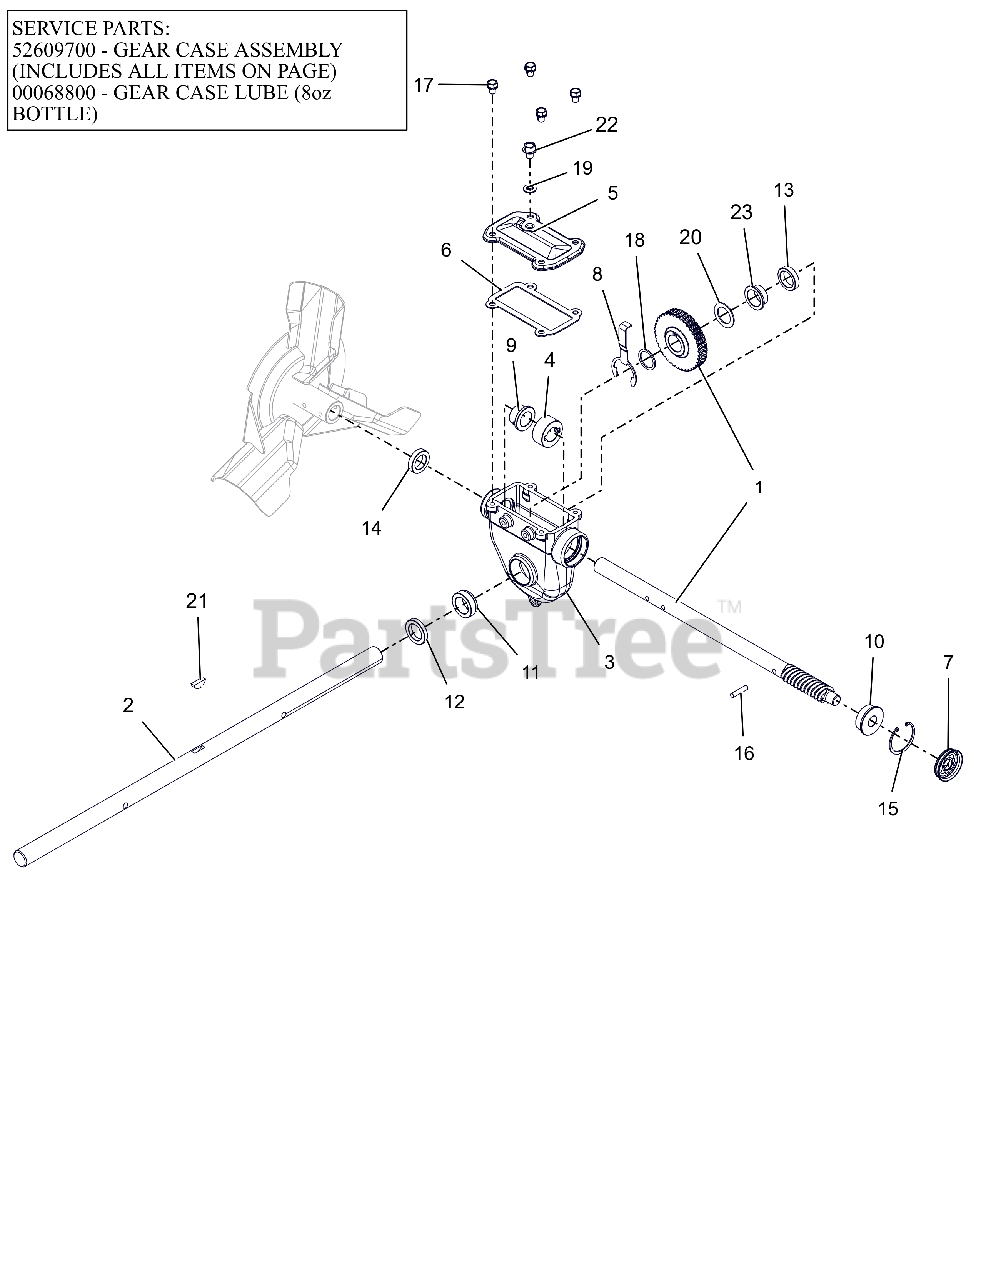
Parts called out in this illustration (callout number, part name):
1	ASSY, WORM SHAFT & GEAR
2	SHAFT, RAKE-28"
3	GEARCASE, LARGE MACHINED
3	GEAR CASE, 28" IRON PRO TOP-LD
3	ARIENS L3 LUBE, 8 OZ BOTTLE
4	THRUST COLLAR, .875"ID SLIPFIT
5	COVER, TOP - LARGE IRON
6	GASKET, TOP - LARGE GEARCASE
7	COVER, GEAR CASE 1.75"
8	BUSHING RETAINER, LARGE
9	BSHG-FLG .879X1.128X.75X1.45
10	BSHG-FLG .628X1.503X.58X1.725
11	BSHG-FLG LARGE, RIGHT
12	SEAL-OIL .999X1.500X.250 TBC29
13	SEAL-OIL .999X1.375X.312 TBC29
14	SEAL-OIL .873X1.375X.312 TBC29
15	RG-RTNG-INT 1.750X.062
16	PIN-STR .250X1.12 6150
17	BOLT, SEMS .31-18X.50 GR5 YWZC
18	WSHR-FL-STL 1.010X1.250X.068YZ
19	WSHR-BND-SEAL .38X.75X.11 GALV
20	WSHR-FL-STL 1.010X1.505X.062YZ
21	KEY-WDRF .25X.875 HRD #A
22	@SCR-ROLOK .38-16X.50 HWH YWZC
23	BSHG-FLG 1.006X1.128X.555X1.45
